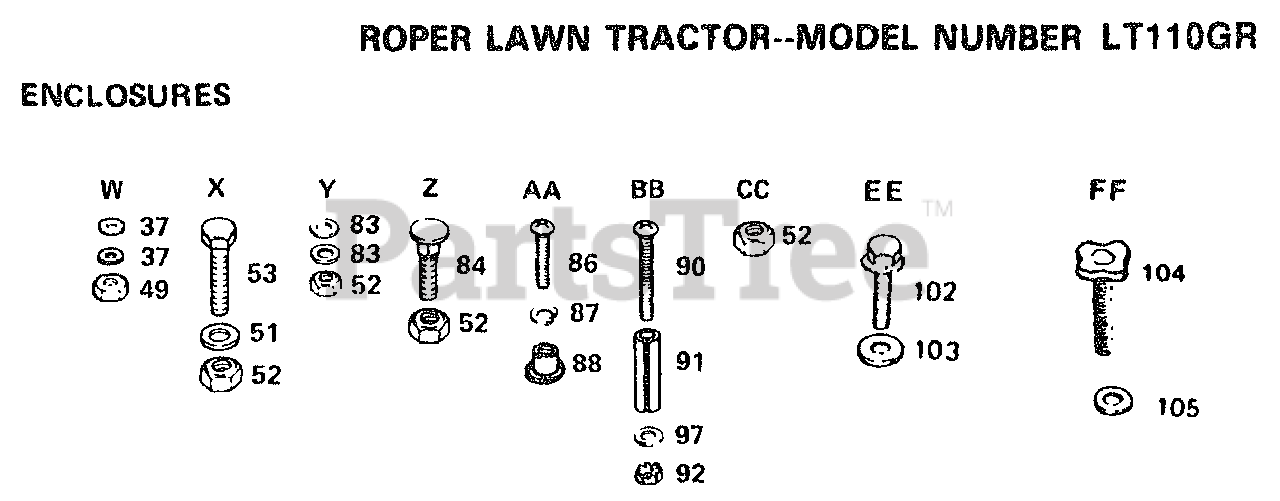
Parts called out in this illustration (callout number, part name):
37	WASHER PM
51	WASHER
53	BOLT
83	WASHER
84	BOLT
86	SCREW
87	LOCKWASHER
88	WELDNUT
90	SCREW
91	SPACER LT
97	WASHER
102	BOLT T
